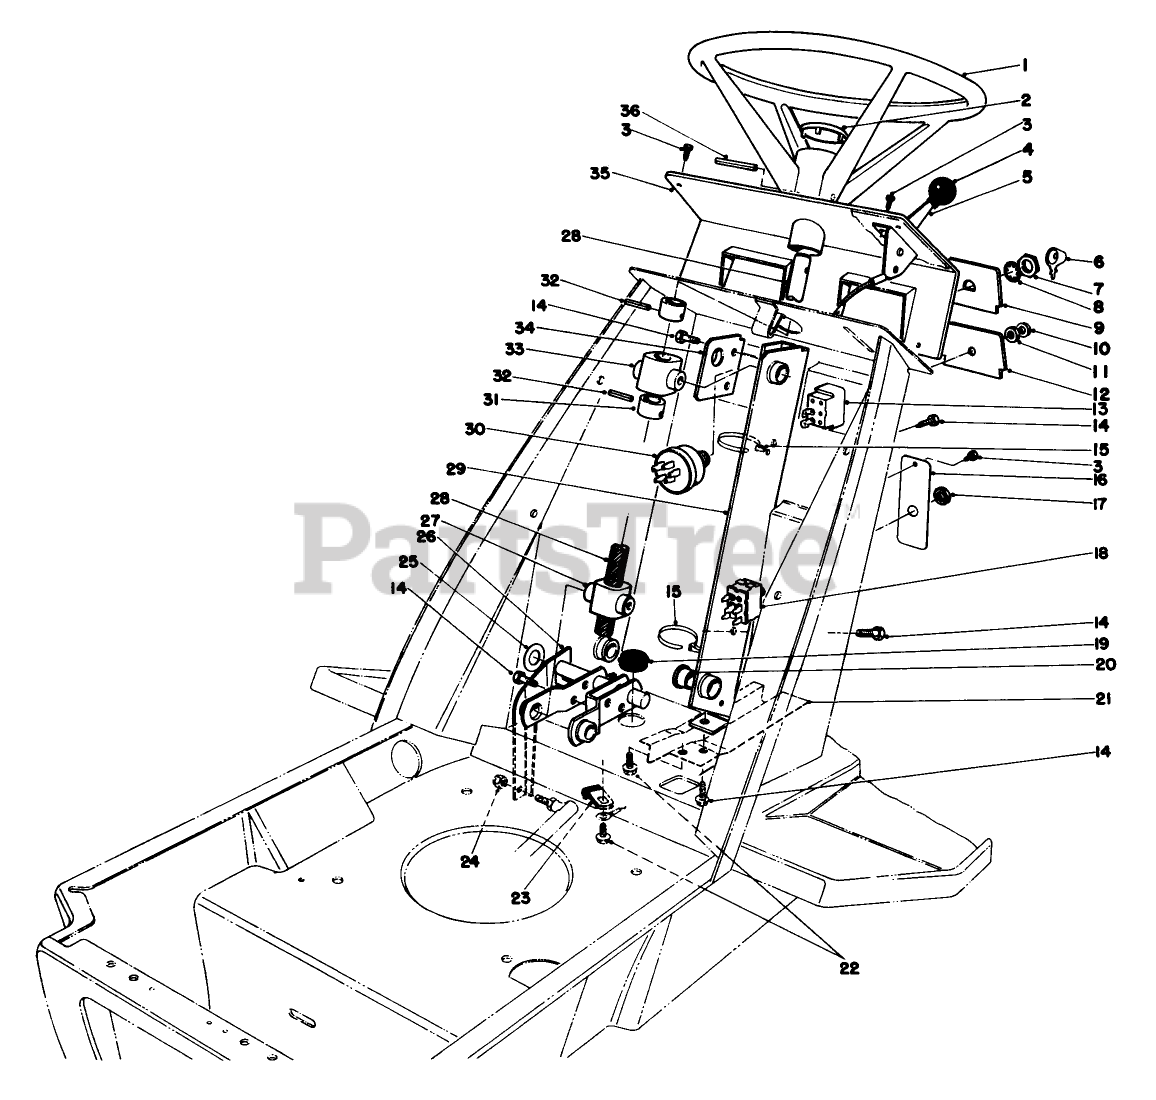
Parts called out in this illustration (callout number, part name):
3	SCREW-HWHTF
4	KNOB-CONTROL
5	THROTTLE CONTROL
7	NUT-HH
8	WASHER-LOCK
11	NUT-LOCK
13	SWITCH-LIGHT
14	SCREW-THD ROLL, HWH
15	TIE-MOUNT, PUSH
19	GROMMET
20	BEARING-FLANGE
22	SCREW-HWH
23	CLIP-FUEL LINE
24	NUT-HEX
28	STEERING SHAFT
30	SWITCH-STARTER
31	STRG SHAFT COLLAR
32	PIN-SPRING
36	PIN-ROLL
